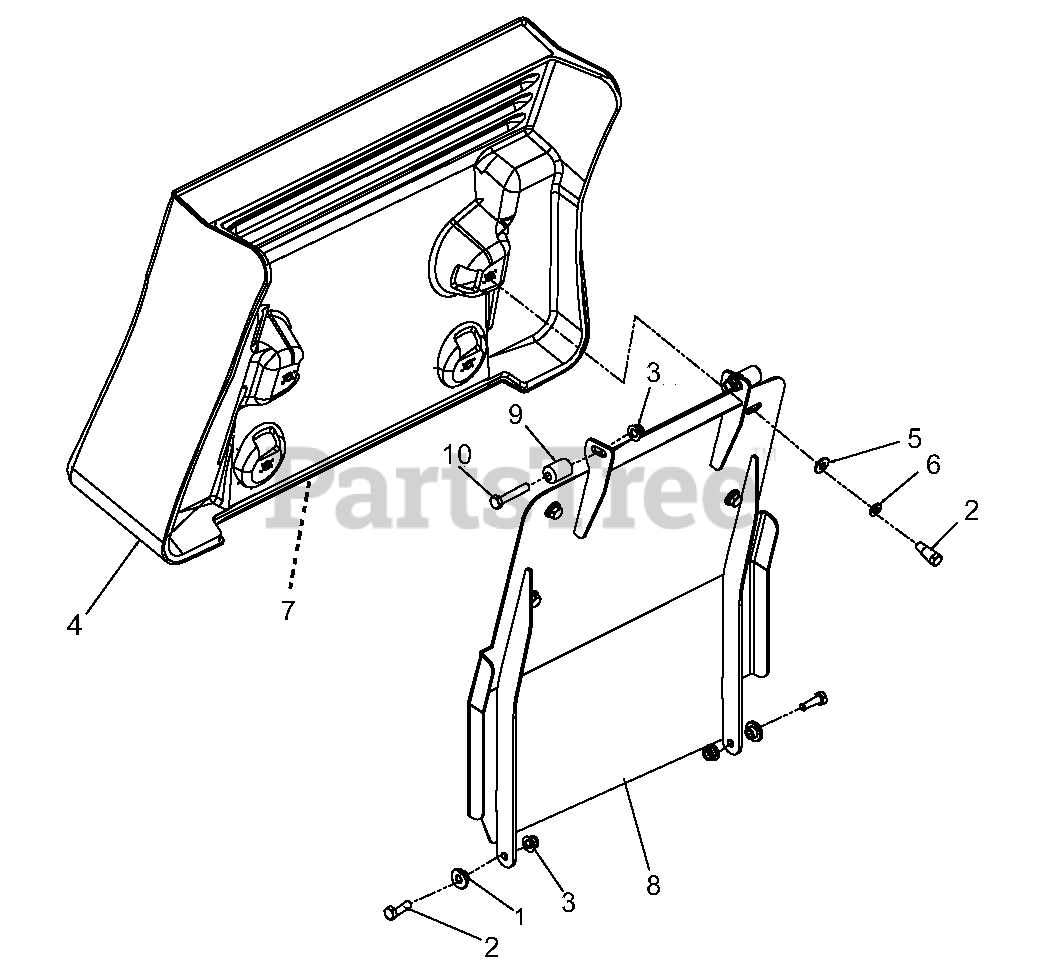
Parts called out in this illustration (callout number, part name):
1	BSHG FLG .312 X .500 X .344
2	BOLT HEX .31-18 X 1.00 GR5 YWZX
3	NUT LK NYL FLG .31-18 YWZC
4	PAD, PROSTANCE
5	WSHR FL STL .312 X .734 .065 YWZ
6	WSHR LK .31 X .078 REG YWZC
7	DECAL, 15" GRAVELY LOGO REV
8	WLDMT, PAD MOUNT
9	ECCENTRIC
10	BOLT HEX .31-18 X 1.75 YWZC
